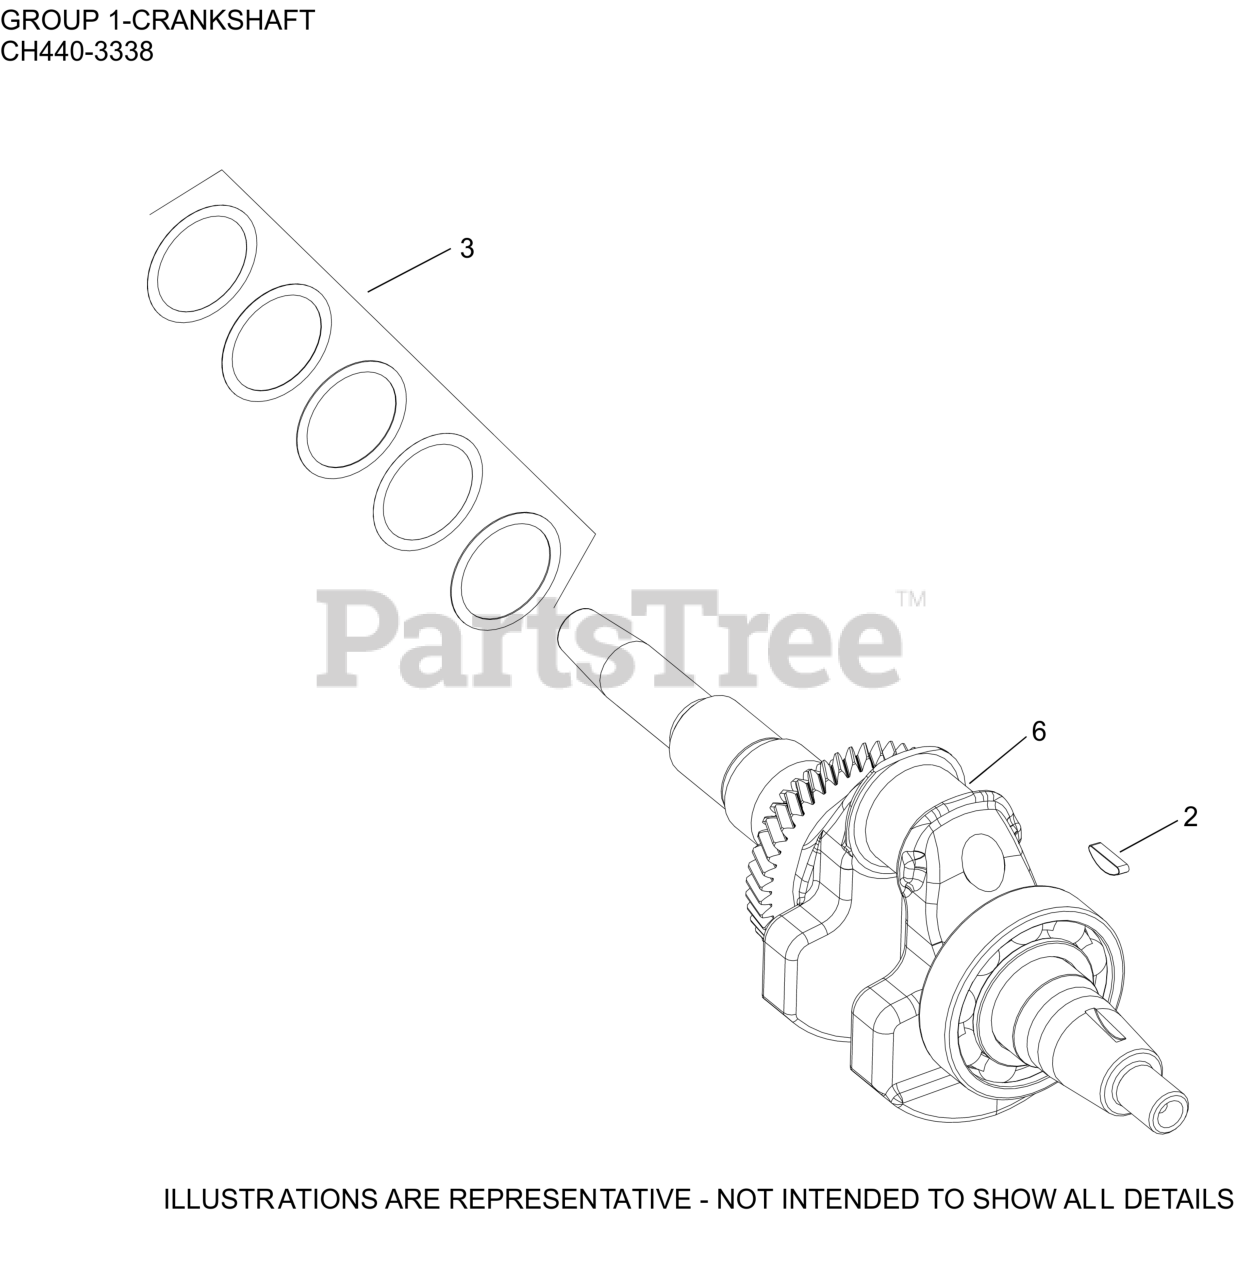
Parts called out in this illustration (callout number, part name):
2	KEY, FLYWHEEL
3	KIT, SHIM
6	CRANKSHAFT ASSEMBLY
